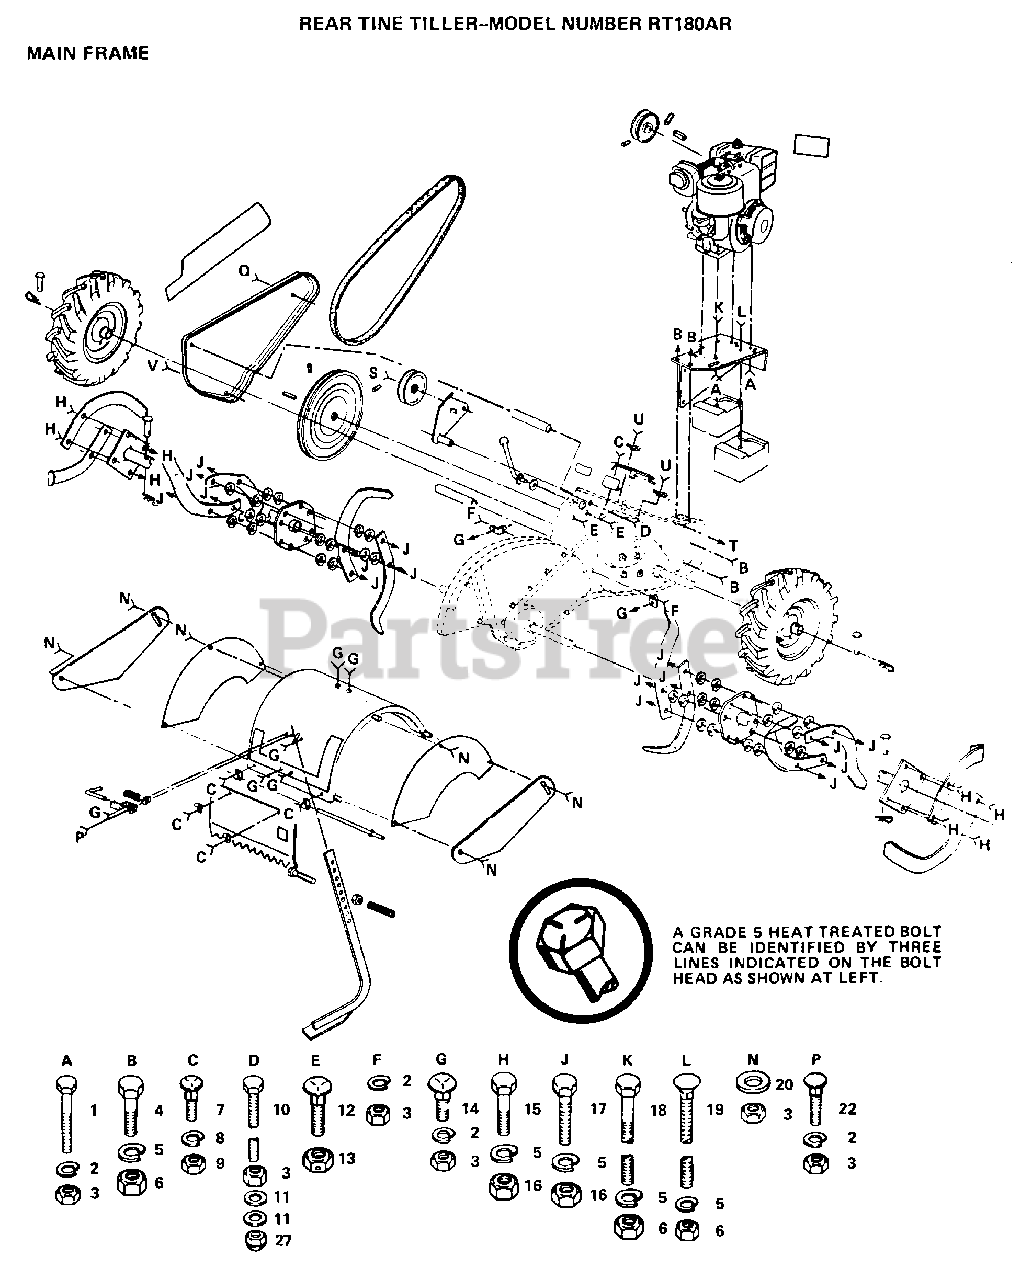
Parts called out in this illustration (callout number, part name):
1	BOLT
2	LOCKWASHER
3	NUT.HEX.5/16-18
4	BOLT
5	LOCKWASHER
6	NUT.HEX.3/8-16UNC
7	BOLT
8	LOCKWASHER
10	BOLT TI
11	WASHER
14	BOLT
15	BOLT
17	BOLT.3/8-24X1-1/2
19	BOLT CRT
20	WASHER
22	BOLT
27	NUT TI
